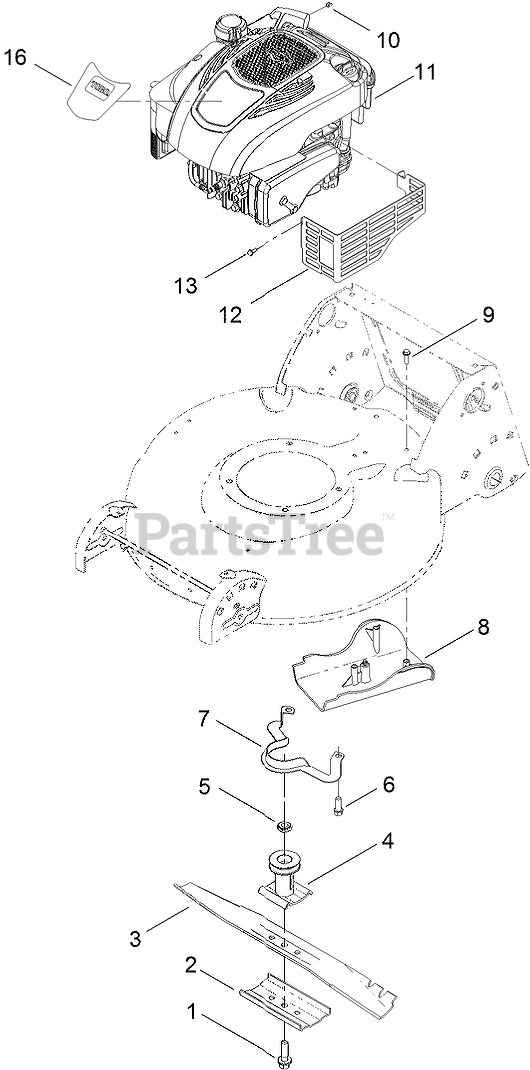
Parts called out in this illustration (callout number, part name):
1	BOLT-BLADE
2	SUPPORT-BLADE
3	BLADE-21 INCH
4	DRIVER-BLADE
5	Spacer-Driver
6	SCREW-TAPTITE
7	Guide-Belt
8	COVER-BELT
9	SCREW-HWH
10	STOP-ROPE
12	SHIELD-MUFFLER
13	SCREW-TAPTITE
16	DECAL-SHROUD
